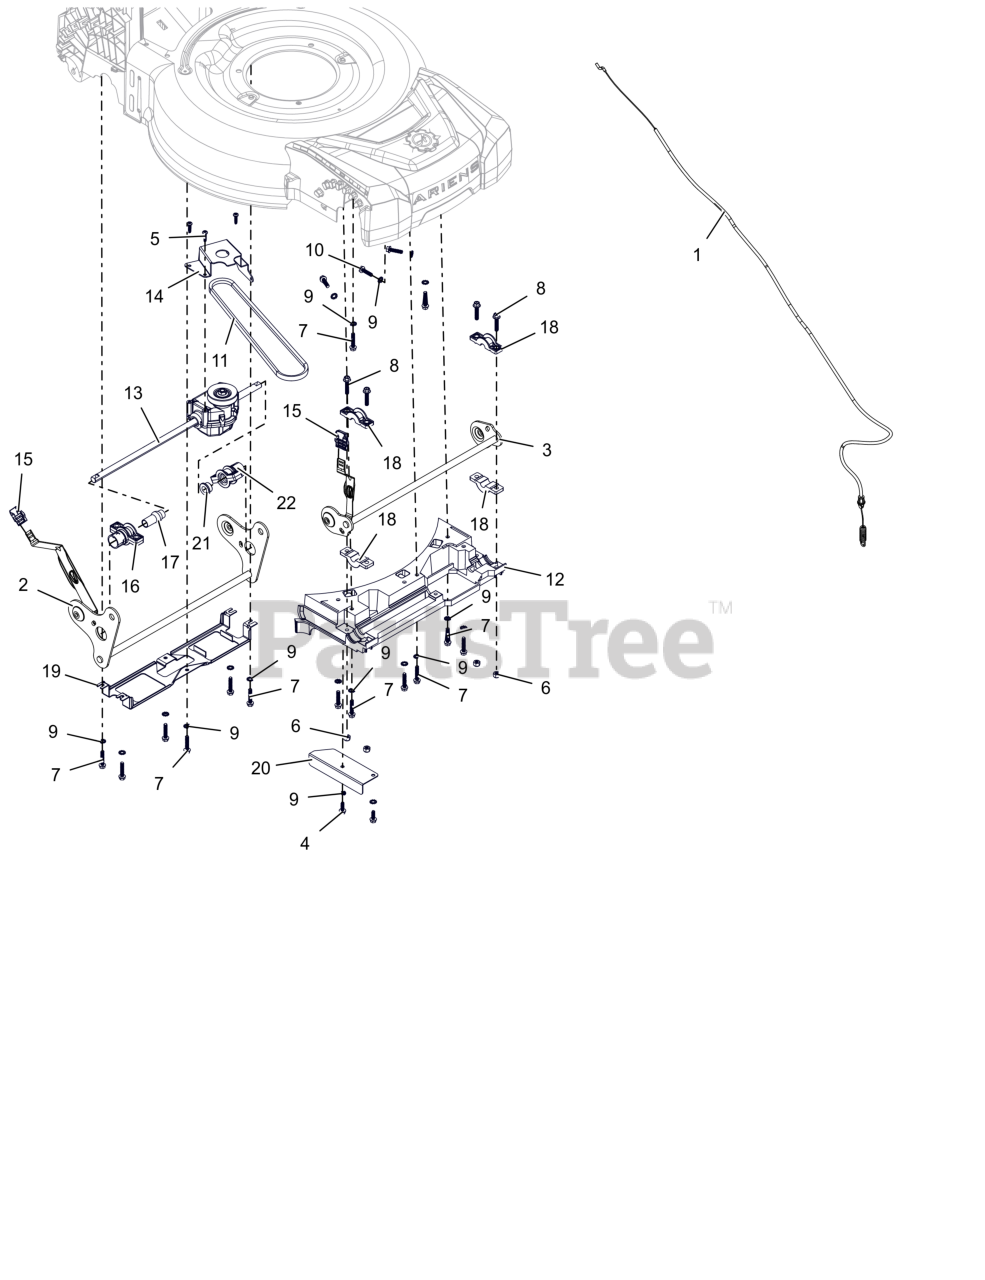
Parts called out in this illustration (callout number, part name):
1	CABLE, RWD TRANSMISSION
2	WLDMT, REAR AXLE - RWD (BLACK)
3	WLDMT, FRONT AXLE - PUSH (BLACK)
4	SCR, HI-LO HWH 1/4-15 X .750
5	SCR, TORX TRILOB PH 10-14X.75
6	NUT, NYLOC 1/4-20
7	SCR, HI-LO HWH 1/4-15 X 1.25
8	BLT, HWH 1/4-20 X 1.25
9	WSHR-LK-EXT, .256X.510X.028
10	SCR, HI-LO HWH 1/4-15 X 1.00
11	BELT, RWD
12	TRAY, FRONT
13	ASM, RWD TRANSMISSION - MA 302
14	BRKT, RWD TRANSMISSION (BLACK)
15	GRIP, HOC
16	BUSHING, AXLE - OUTER
17	BUSHING, AXLE - INNER
18	BUSHING, SHAFT - HOC
19	BRKT, RWD BACK SUPPORT (BLACK)
20	FLANGE, BLOW OUT (BLACK)
21	BUSHING, FLANGE 1.00X.500X.500
22	BUSHING, AXLE - OUTER LH
